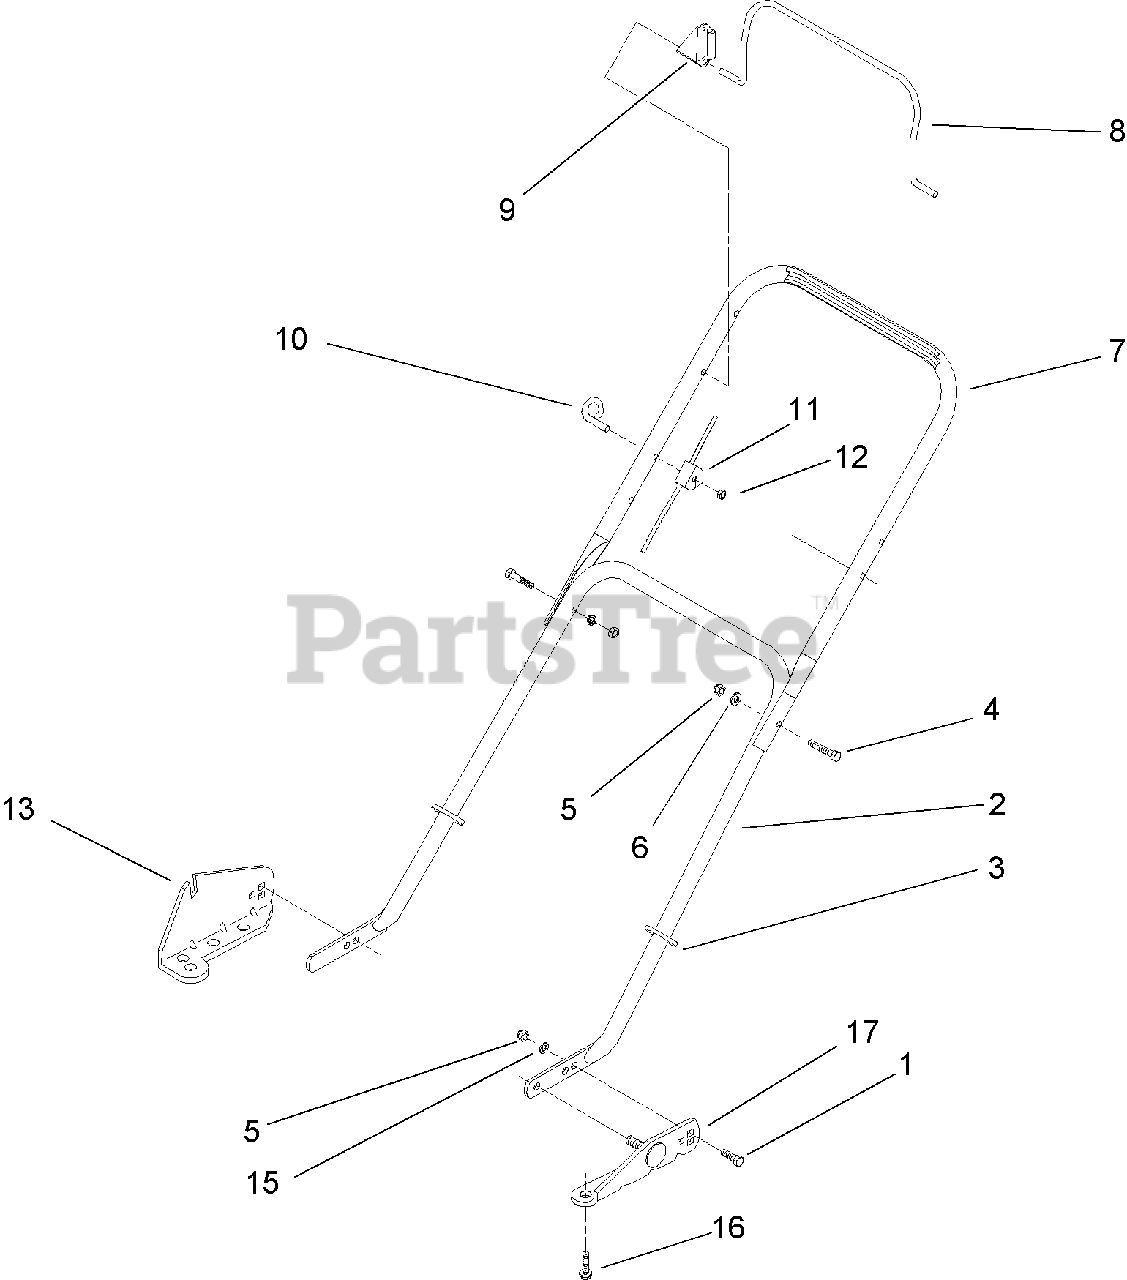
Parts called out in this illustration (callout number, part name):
1	SCREW-CARR
2	HANDLE-SECTION, LOWER
3	STRAP-TIE
4	SCREW-HH
5	NUT-LOCK, NI
6	WASHER-CURVED
7	HANDLE-UPPER
8	BAIL CONTROL LEVER ASM
9	STOP-PIVOT
10	GUIDE-ROPE
11	BRAKE CABLE ASM
12	NUT-LOCK, NI
13	RH BRACKET and PIN ASM
15	WASHER-FLAT
17	LH BRACKET and PIN ASM
